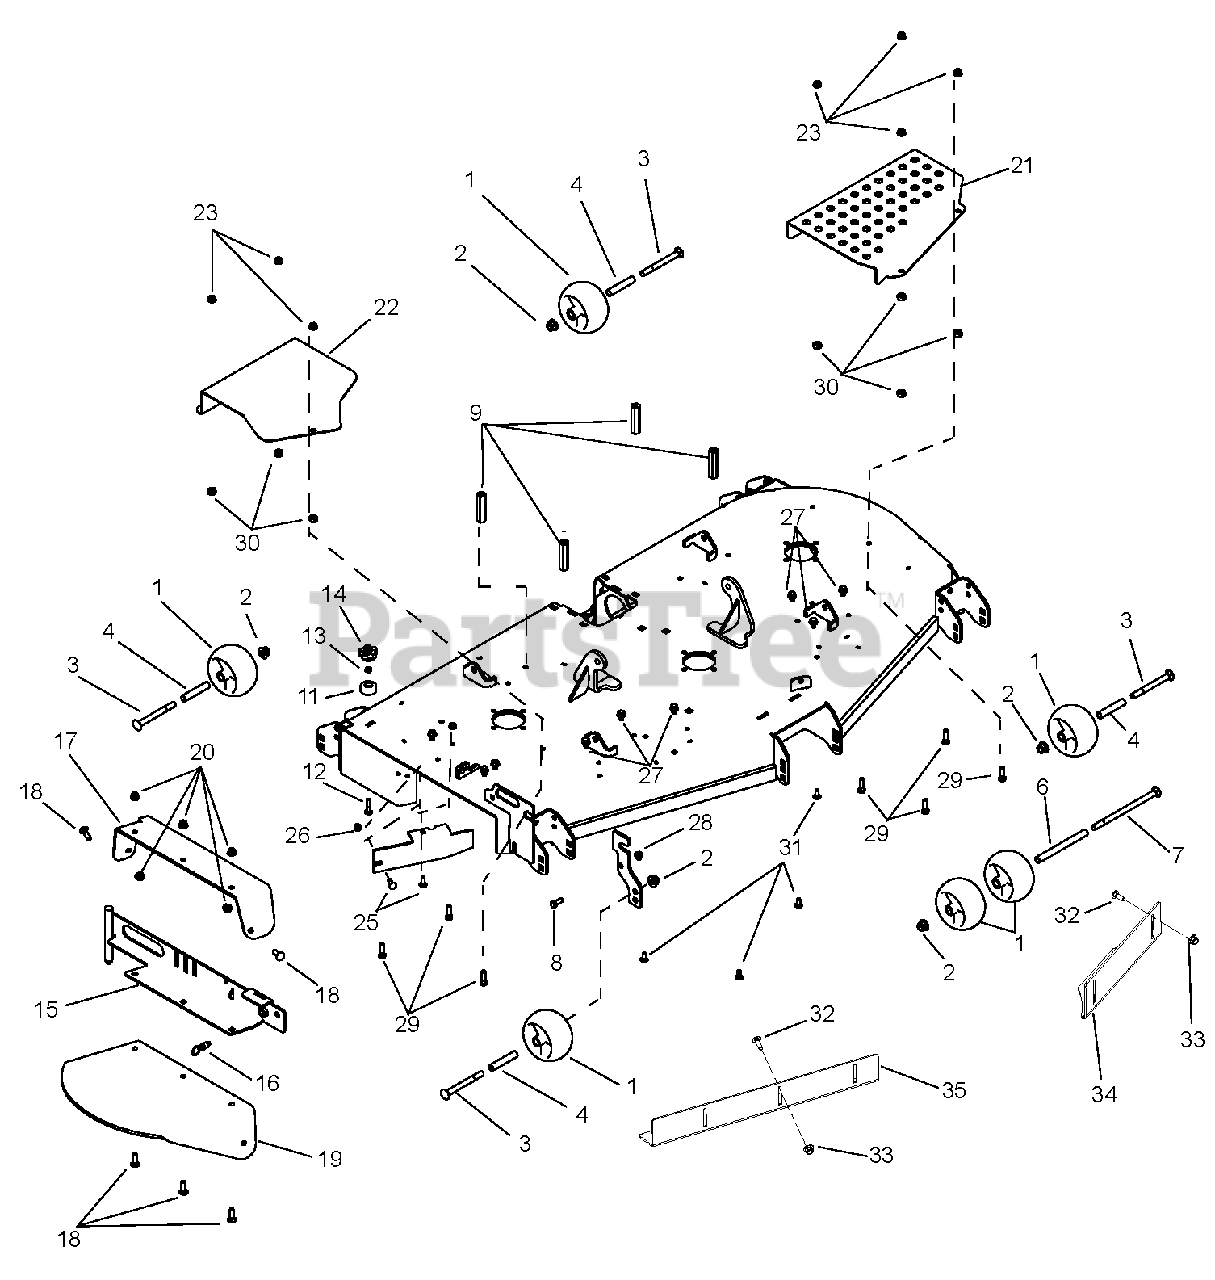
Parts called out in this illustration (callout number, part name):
1	Wheel, Antiscalp
2	Nut, Nyloc Flange .50-13
3	Bolt, Round Head Square Neck .50-13 x 5.00 YZ
4	Spacer, .510 x .625 x 3.35
5	Chute Storage Bracket- Red
6	Spacer, .510 x .625 x 6.70
7	Bolt, Round Head Square Neck .50-13 x 8.50
8	Bolt, Hex .38-16 x 1.00
9	Nut-Coupling .31-18 x 3.00
10	60" Discharge Baffle-Red
11	Bumper, Recessed 1.50 x .63
12	Bolt, Round Head Square Neck .31-18 x 1.50
13	Nut, Locking-Center .31-18
14	Knob, Clamping .312-18 Nyloc
15	52"– 60" Discharge Chute Mounting Weldment-Red
16	Pull Pin, .50-13 Thread x .310 Diameter Plunger
17	Rubber Discharge Chute Support-Red
18	Bolt, Round Head Square Neck .38-16 x 1.25
19	Chute, Rubber Discharge
20	Nut, Nyloc Flange .38-16
21	Guard, 60" Left Hand Spindle
22	Guard, 60" Right Hand Spindle
23	Bolt, SEMS .31-18 x .62
24	Washer, Internal Lock .375
25	Bolt, Round Head Square Neck .31-18 x 1.00
26	Nut, Nyloc Flange .31-18
27	Screw, Tapping .38-16 x .50
28	Nut, Center-Lock .38-16
29	Bolt, Hex .38-16 x 1.25
30	Nut, Heavy Hex .38-16
